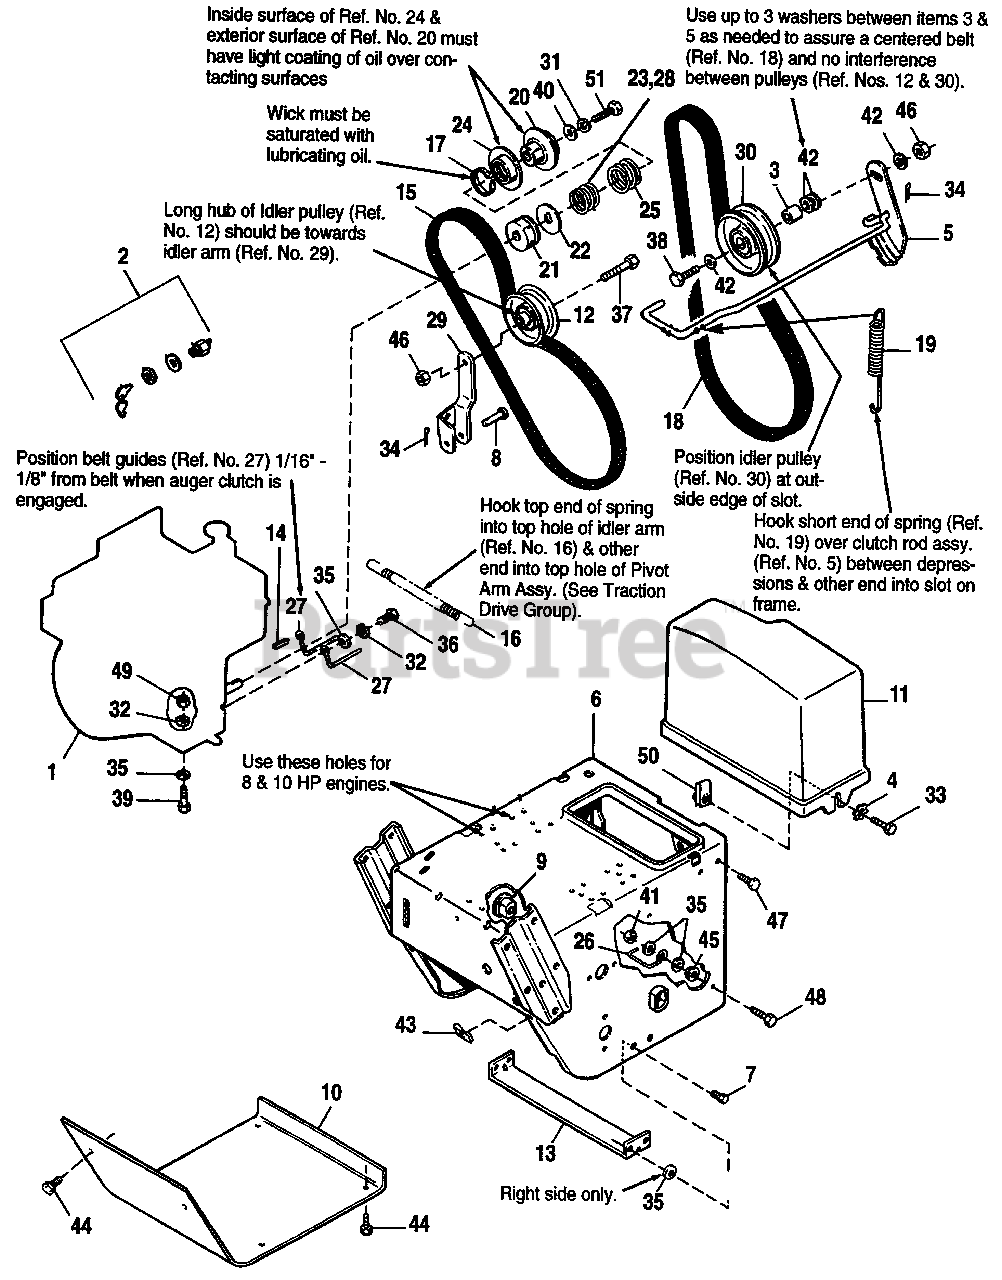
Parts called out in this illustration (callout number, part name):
1	ENGINE, Tecumseh
2	IGNITION SWITCH ASSY.
4	LOCKWASHER, Ext. Tooth, 5/16
5	CLUTCH ROD & BRAKE ASSY.
6	FRAME, Main
7	SCREW, Taptite, 5/16-18 x 3/8
8	PIN
9	BUSHING, Axle
10	COVER, Bottom
11	GUARD, Belt
12	PULLEY, Idler
13	SUPPORT, Tie Bar
14	KEY, Parallel, 3/16 x 13/16 x 7/8
15	BELT, Traction
16	SPRING, Idler
18	BELT, Auger Drive
19	SPRING, Extension
20	PULLEY, Half Drive
21	PULLEY, Traction
22	WASHER, Thrust
23	SPRING, Compression (Model 10-80)
24	PULLEY, Half
25	SPRING, Compression
27	BELT GUIDE
28	SPRING, Compression (Model 8-70 & 9-70)
29	ARM, Idler, Traction
30	PULLEY ASSY.
31	LOCKWASHER, Spring, 3/8
32	LOCKWASHER 5/16
33	SCREW, Truss Hd., 5/16-18 x 3/4
34	PlN, Cotter, 1/8 x 3/4
35	WASHER, 11/32 x 3/4
36	CAPSCREW, Hex. Hd., 5/16-24 x 3/4
37	CAPSCREW, Hex Hd., 3/8-16 x 1-1/2
38	CAPSCREW, Hex Hd., 3/8-16 x 1-3/4
39	CAPSCREW, Hex Hd., 5/16-18 x 2
40	WASHER, 13/32 x 1
41	NUT, Hex, Centerlock, 5/16-18
42	WASHER, Flat, 13/32
43	NUT, Speed, 1/4-20
44	SCREW, Taptite, 1/4-20 x 3/8
45	NUT, Hex, Whizlock 5/16-18
46	LOCKNUT, Jam, 3/8-16
47	CAPSCREW, Whizlock 5/16-18 x 3/4
48	CAPSCREW, Whizlock 5/16-18 x 1-1/4
49	NUT, Hex, 5/16-18
50	NUT, Speed, 5/16-18
51	CAPSCREW, Hex Hd., 3/8-24 x 2
